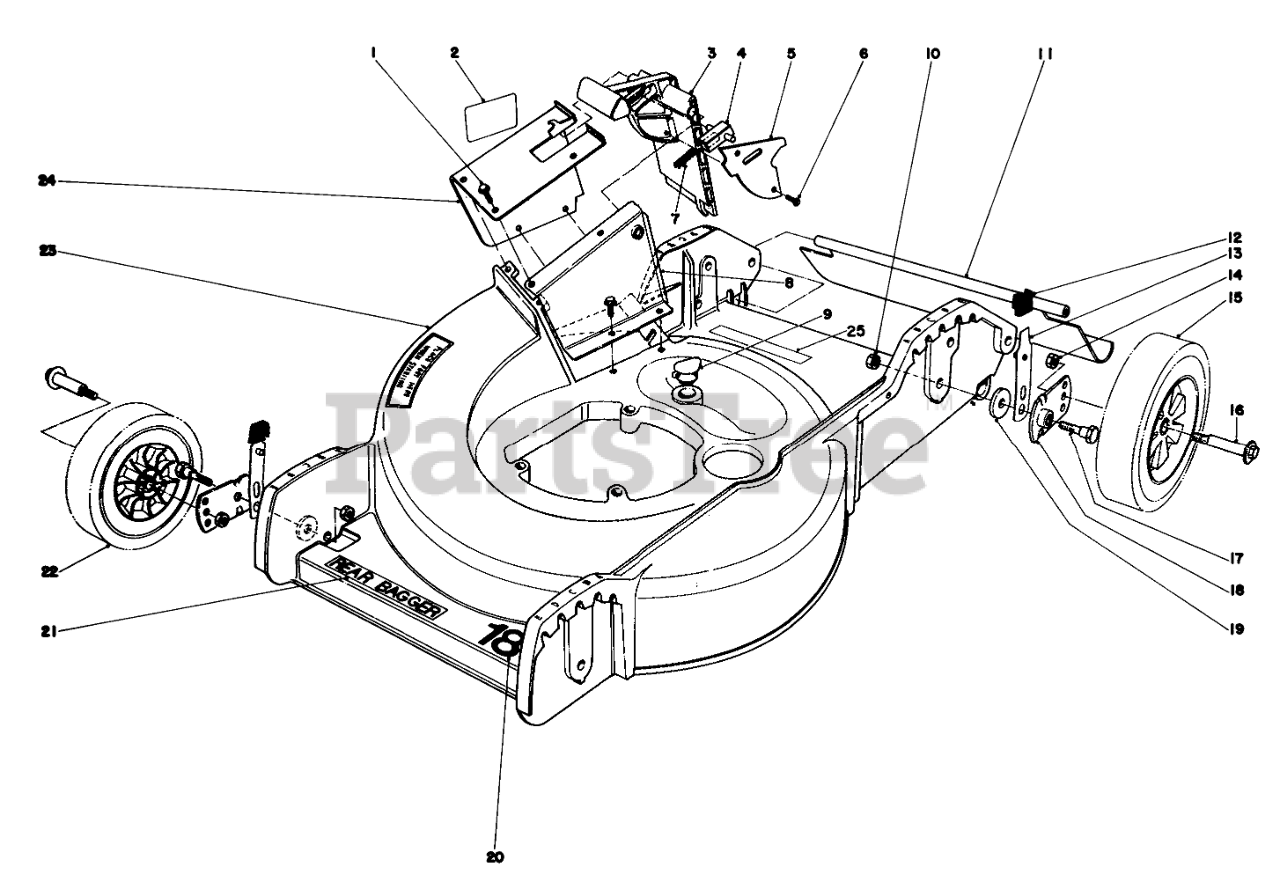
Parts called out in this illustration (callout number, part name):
1	SCREW
2	Decal Door (French & Dutch)
3	Door Mulching
4	Door Latch
5	Cover Door
7	SPRING-COMPRESSION, LATCH
8	Inner Tunnel
9	WASHOUT PLUG
10	Nut
11	SHIELD - TRAILING
12	KNOB-ARM
13	SPRING ARM ASM
14	Nut
15	WHEEL & TIRE ASM
16	BOLT-WHEEL
17	PIVOT SCREW
18	PIVOT ARM ASSY
19	PIVOT WASHER
20	Decal
21	DECK DECAL
22	Wheel & Tire Assembly
23	Housing
24	Tunnel Outer
25	Decal-Noise (French)
